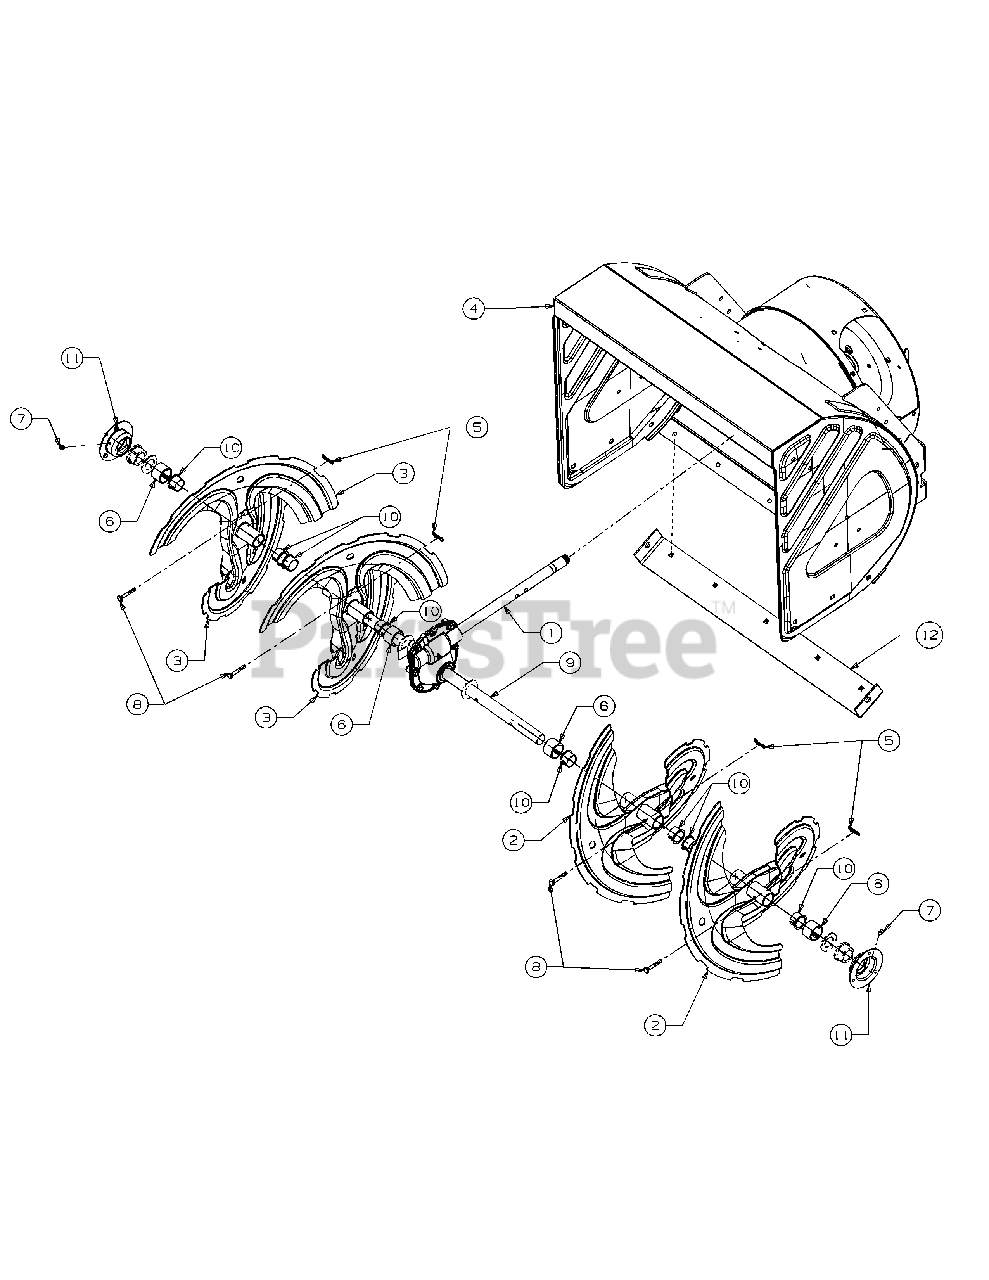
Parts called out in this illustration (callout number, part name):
1	Gear Assy-Auger
2	Spiral Asm:LH 900
3	Spiral Asm:RH 900
4	Housing Assy-Auger
5	Pin-Cotter
6	Spacer
7	Grease Fitting
8	Shear Pin .25X150
9	Axle:Spiral
10	Bushing
11	Housing:Bearing
12	Plate-Shave 28"
